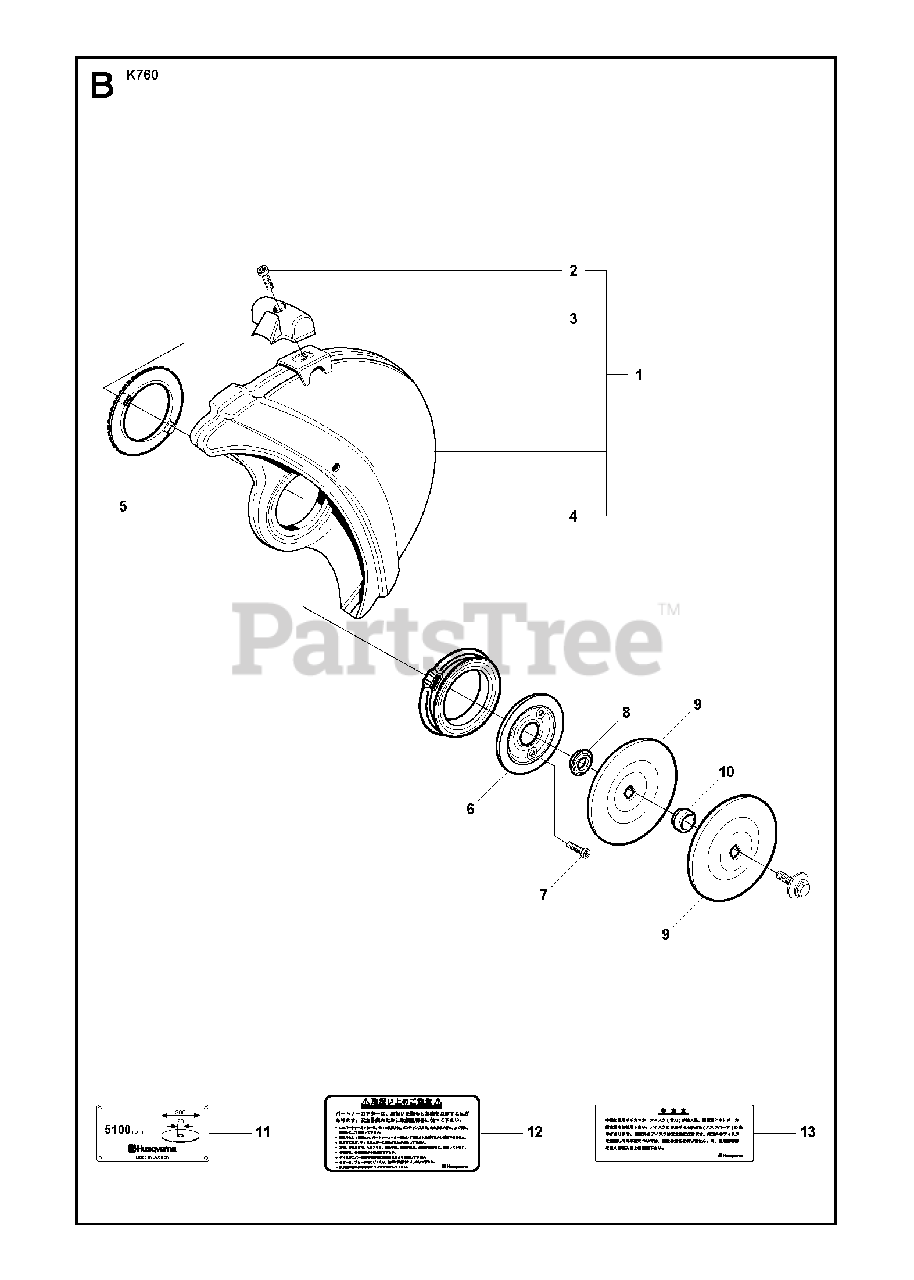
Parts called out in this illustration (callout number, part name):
1	BLADE GUARD"12"", Incl. 2 - 4"
1	BLADE GUARD"14"", Incl. 2 - 4"
2	SCREW ITXSCM
7	SCREW ITXSCM
8	SUPPORT FLANGE
9	FLANGE WASHERDiam 105 mm
9	FLANGE WASHERDiam 119 mm
10	KITDiam 20 mm
10	KITDiam 22,2 mm
10	KITDiam 25,4 mm
10	BUSHINGDiam 30,5 mm
11	LABEL"12"", Diam 1"""
11	LABEL"12"", Diam 20 mm"
11	LABEL"14"", Diam 1"""
11	LABEL"14"", Diam 20 mm"
